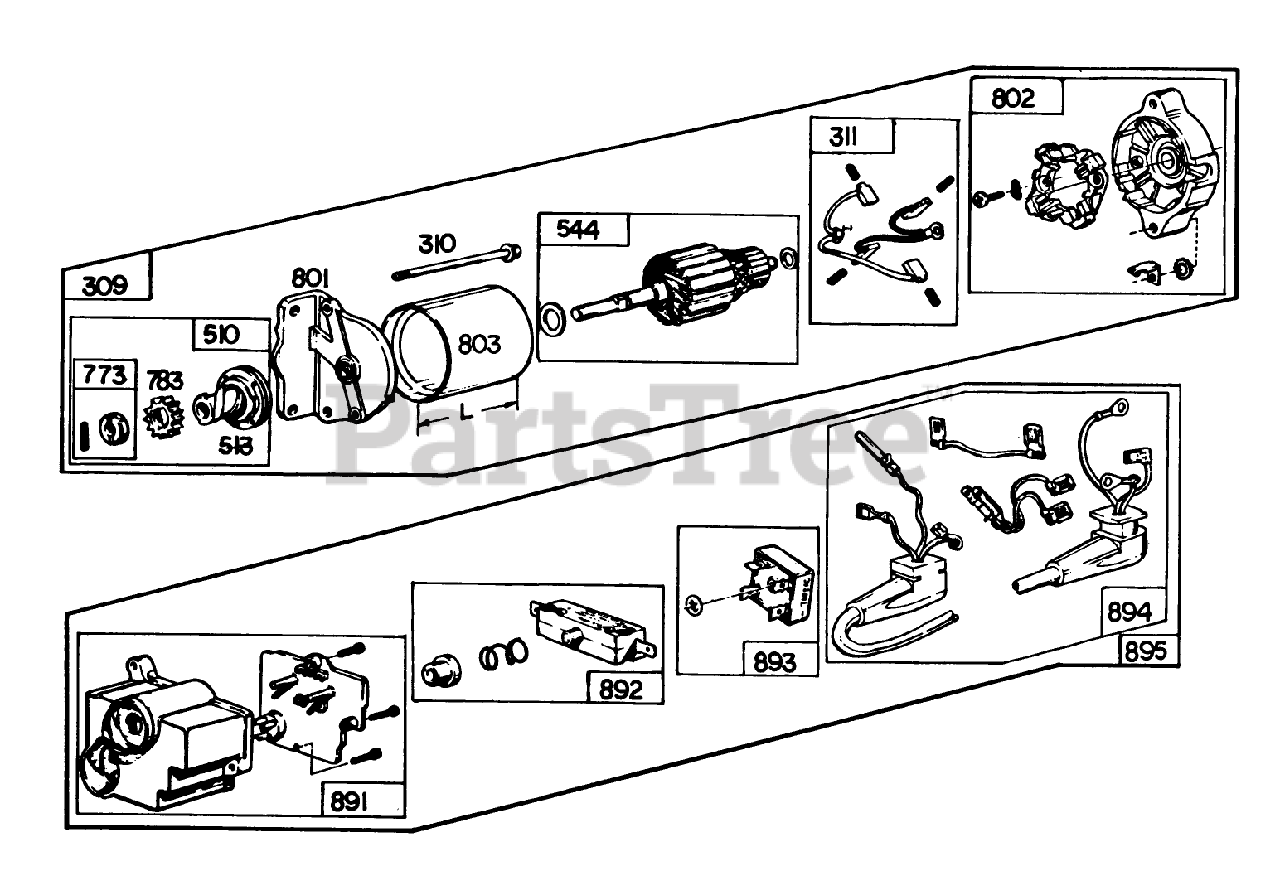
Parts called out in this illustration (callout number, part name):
309	Motor Drive Assembly
310	Thru Bolt Assembly
311	Brush Assembly
510	Drive Assembly
513	Clutch Assembly
544	Armature Assembly
773	Gear-Starter
801	Drive End Cap Assembly
802	Comm. End Cap Assembly
803	Housing Assembly
891	Housing Group
892	Switch Group
893	Rectifier
894	Lead Group
895	Control Group
